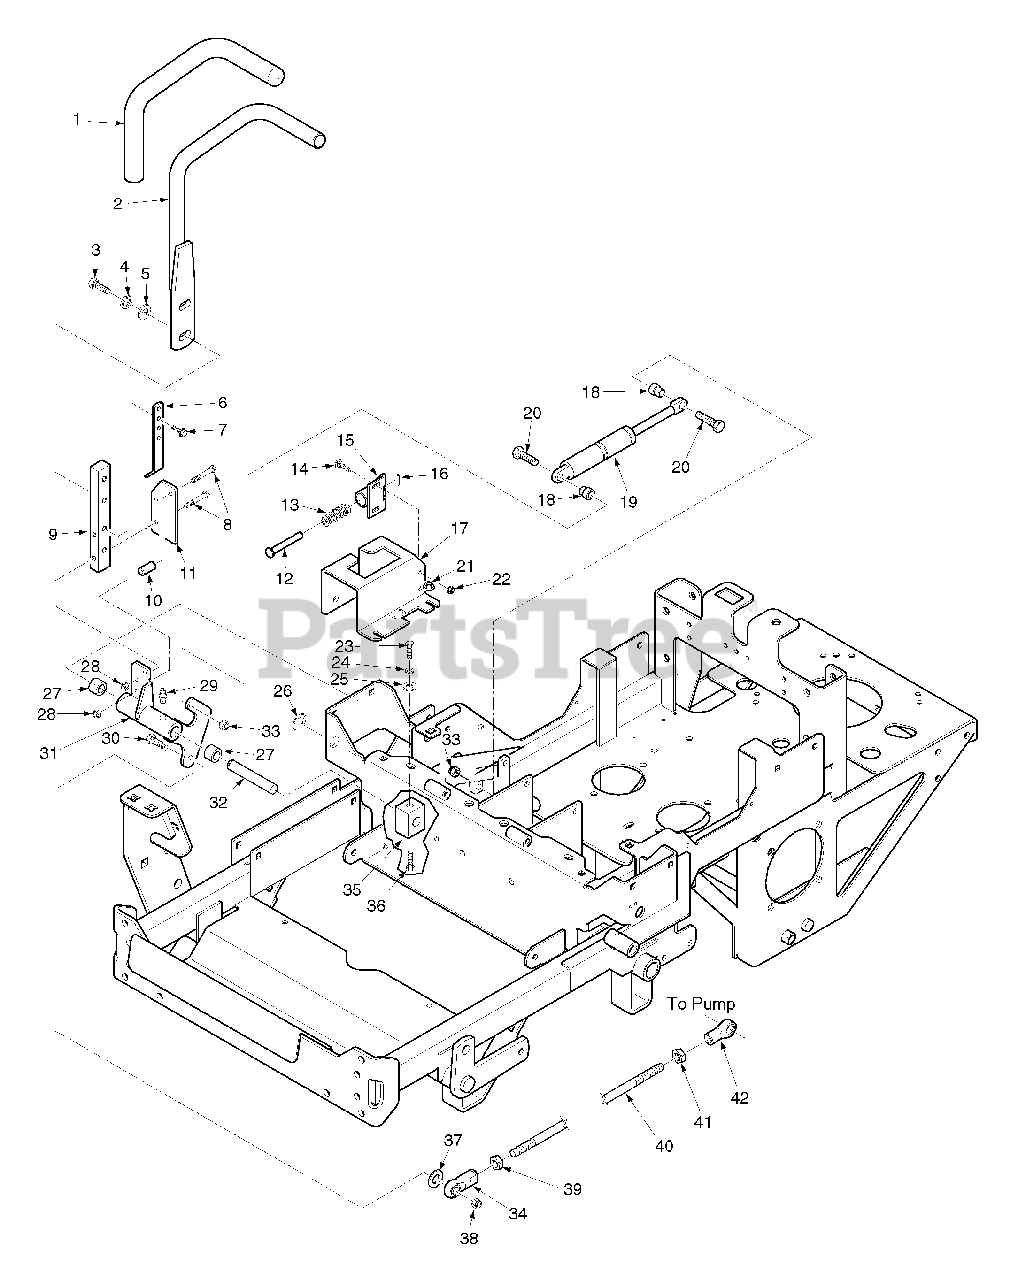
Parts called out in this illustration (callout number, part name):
1	Grip, Control Lever
2	Handle Bar
3	Bolt, Hex Head 3/8-16 x 1-1/4"
4	Lock Washer, 3/8"
5	Flatwasher, 3/8-.391 x .938 x .105
6	Bracket, Switch Actuator
7	Bolt, Hex Serr. Flange 5/16-18 x 3/4"
8	Bolt, Hex Head 5/16-18 x 2"
9	Bar, Control Lever
10	Spacer, Control
11	Plate, Control Lever
12	Pin Retainer
13	Spring
14	Bolt, Carr. 1/4-20 x 3/4"
15	Bracket, Control Return
16	Roll Pin, Spring 5/32 x 3/4"
17	Control Bracket with Decal, L.H.
18	Spacer, Pump Dampener
19	Gas Damper
20	Bolt, Hex Head 5/16-18 x 1-3/4"
21	Nut, Serr., Flange, 5/16-18
22	Nut, Elastic Stop 1/4-20
23	Bolt, Hex Head 3/8-16 x 3/4"
24	Lock Washer, 3/8"
25	Flatwasher, 3/8-.391 x .938 x .105
26	Retaining Ring, 3/4" Ext.
27	Bushing, .753 ID
28	Nut, Elastic Stop 5/16-18
29	Grease Fitting, 1/4-28 Self Tap
30	Bolt, Hex Head 3/8-16 x 1-1/2"
31	Linkage Bellcrank Assembly R.H.
32	Shaft, Steering Control
33	Nut, Elastic Stop 5/16-18
34	Rod End, 3/8-24 RH Female
35	Block, Clamping
36	Bolt, Hex Head 3/8-16 x 1"
37	Flatwasher, 3/8-.391 x .938 x .105
38	Nut, Elastic Stop 3/8-16
39	Nut, 3/8-24 RH Thread
40	Link, Pump 3/8-24 x 10.89"
41	Nut, 3/8-24 UNF-2B LH Thread
42	Rod End, 3/8-24 LH Thread
